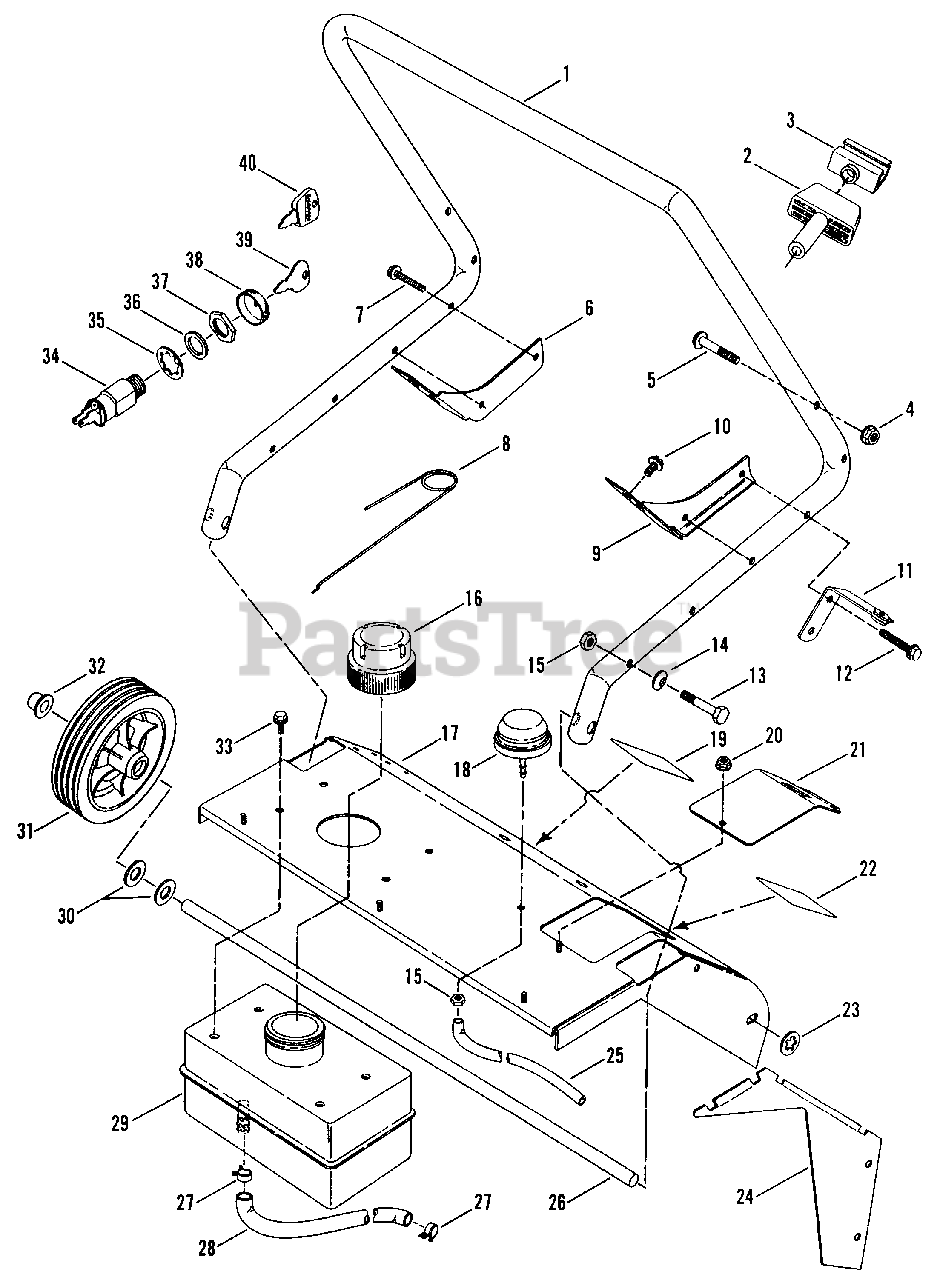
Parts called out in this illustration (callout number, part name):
1	HANDLE, Lower
2	HANDLE, Rope Starter
3	INSERT, Rope Start Handle
4	NUT, 1/4-20 Hex Flange Lock
5	BOLT, 1/4-20 x 1 3/8" Square Neck Carriage, Grade 5
6	BRACE, Handle (Right Hand)
7	SCREW, 1/4-20 x 1-1/4" Hex Washer Self-Tap
8	CONTROL, Choke
9	BRACE, Handle (Left Hand)
10	SCREW, #10-32 x 1/4" Hex Washer Self-Tap
11	ASSEMBLY, Bracket & Bushing
12	SCREW, 1/4-20 x 1-3/8" Hex Washer Self-Tap
13	SCREW, 1/4-20 x 1-1/4" Hex Head Cap, Grade 5
14	WASHER, 1/4" Curved
15	NUT, 1/4-20 Hex Center Lock
16	CAP, Fuel Tank
17	WELDMENT, Handle/Panel
18	PRIMER, Fuel
19	DECAL, Model
20	NUT, #10-24 Hex Flange Lock
21	COVER, Access Hole
22	DECAL, Control Panel
23	RETAINER, 1/4" Bolt
24	BAFFLE, Left Hand
25	HOSE, Primer
26	AXLE
27	CLAMP, Fuel Line
28	LINE, Fuel
29	TANK, Fuel
30	WASHER, 3/8" Flat
32	NUT, 3/8 Push
33	SCREW, 1/4-15X3/4, Self-Tapping, BZ
34	SWITCH, Ignition (2 pole)
35	WASHER, 5/8 Internal Tooth Lock
36	SPACER
37	NUT, 5/8-32 Hex (Special)
38	BEZEL
39	KEY, Ignition
40	KEY, Switch (With Cover)
